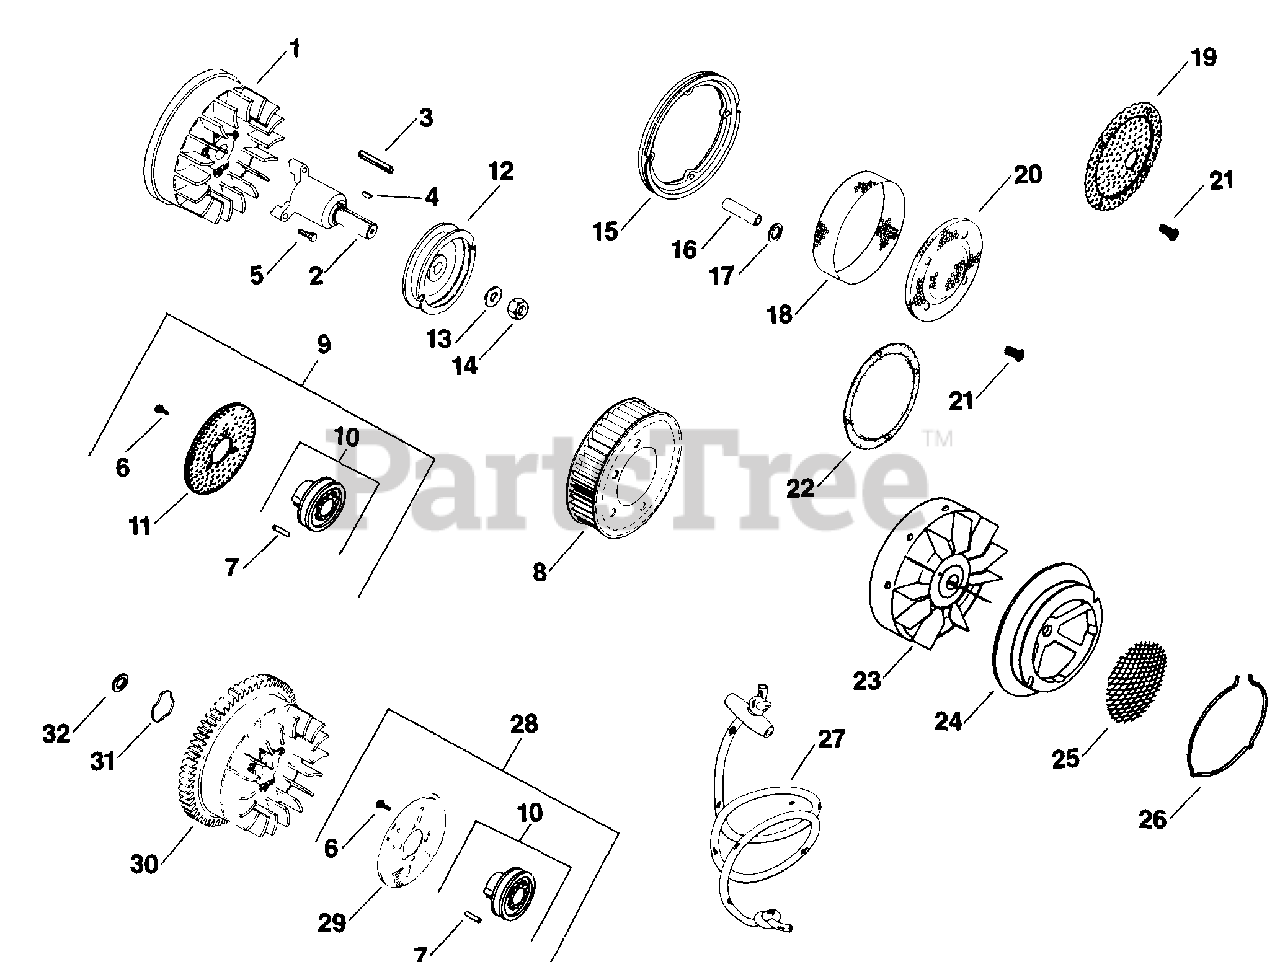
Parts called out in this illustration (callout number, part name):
13	WASHER USE 25 468 06-S
14	NUT, 5/8 GRADE 2 - DISCONTINUED
27	ROPE-DISCONTINUED
